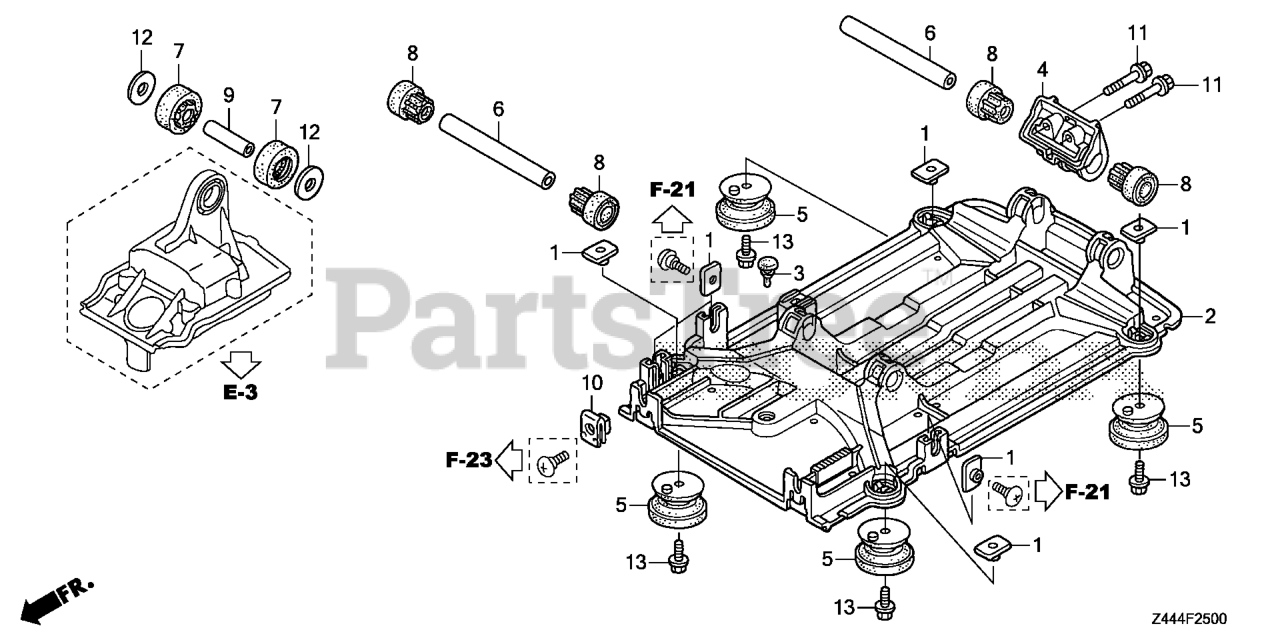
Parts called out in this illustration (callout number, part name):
1	NUT, SPECIAL (6MM)
2	COVER (LOWER)
3	GROMMET, PAD SETTING
4	BRACKET, ENGINE MOUNTING
5	RUBBER (LOWER)
6	COLLAR A, INSULATOR
7	INSULATOR (UPPER)
8	INSULATOR (LOWER)
9	COLLAR B, INSULATOR
10	NUT, FENDER SETTING
11	BOLT, FLANGE (6X32)
12	WASHER, PLAIN (10MM)
13	BOLT, FLANGE (6X10)
